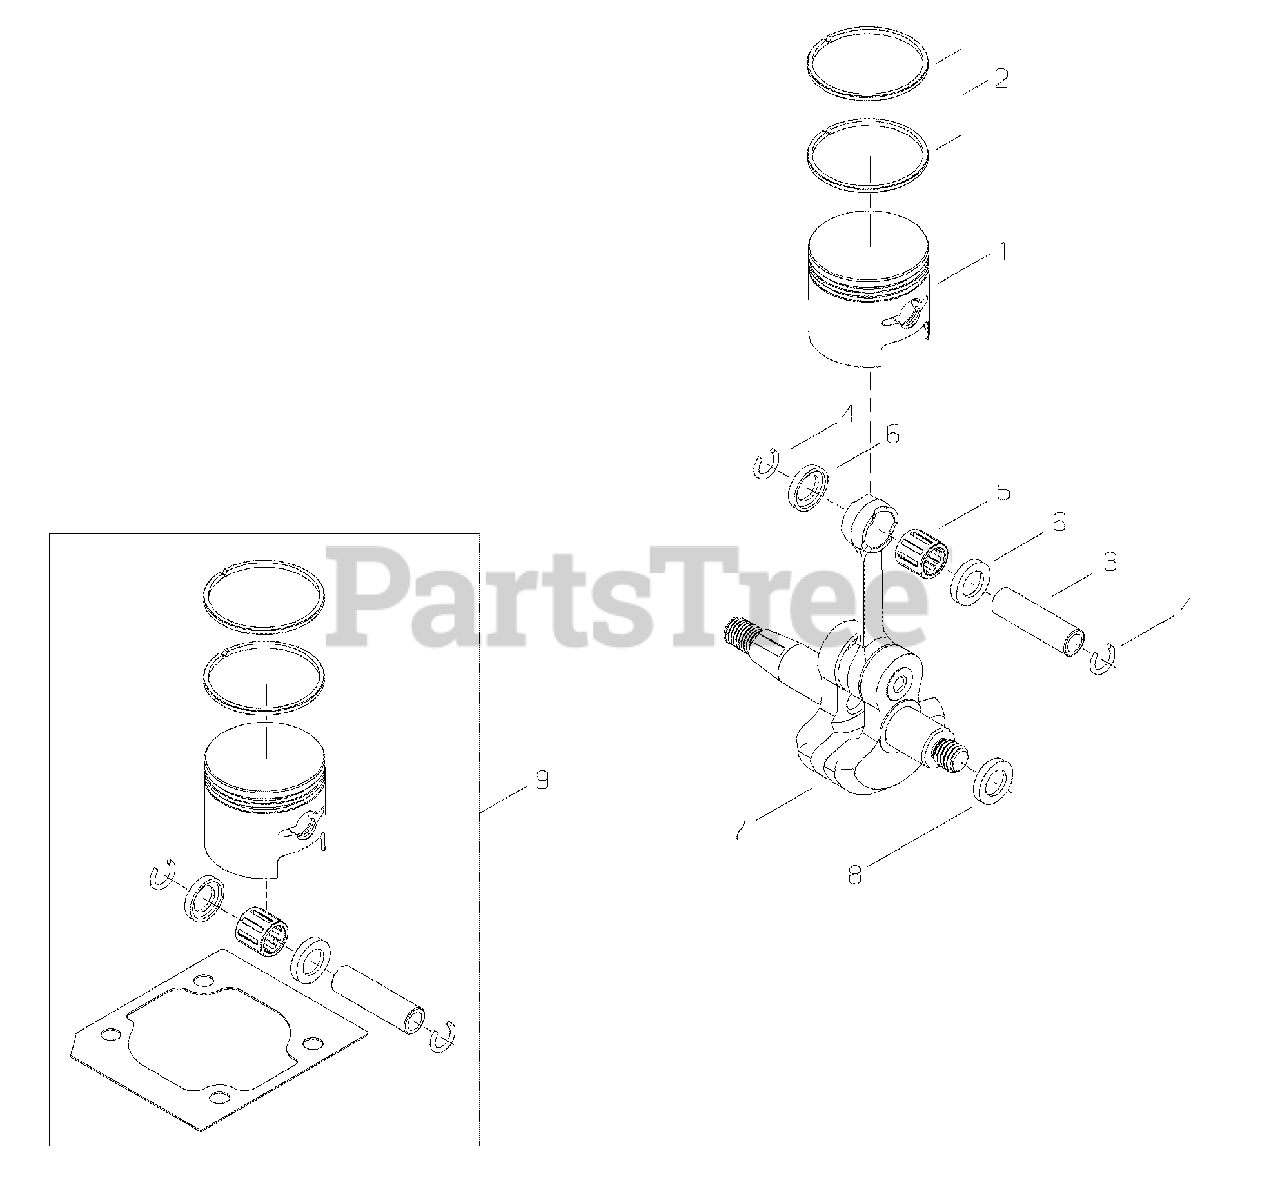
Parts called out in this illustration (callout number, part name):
1	PISTON
2	RING, PISTON
3	PIN, PISTON
4	RING, RETAINING
5	BEARING, NEEDLE
6	WASHER, THRUST
7	CRANKSHAFT ASSY
8	SHIM
9	PISTON KIT
